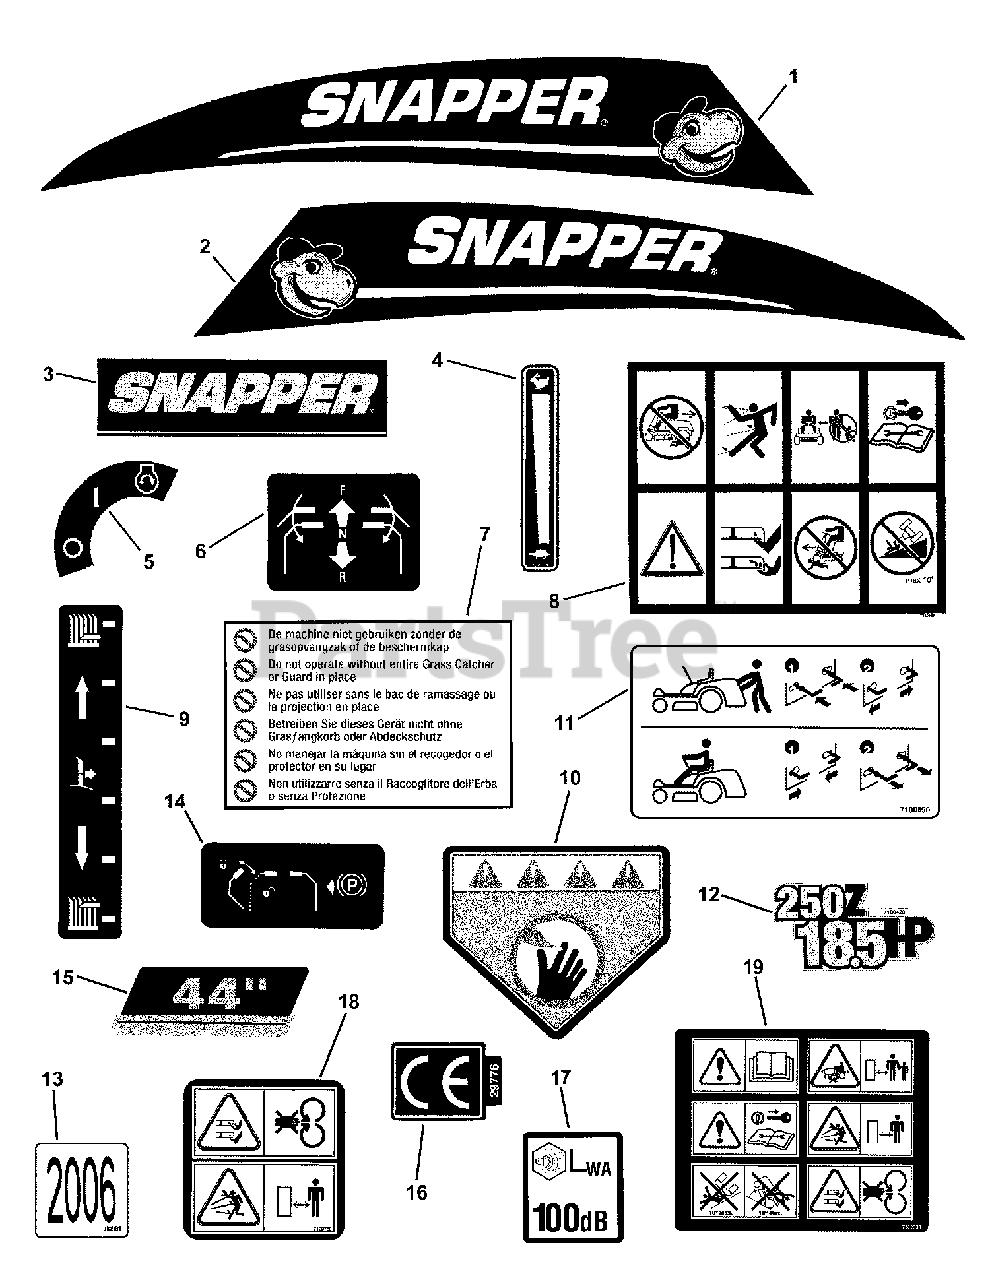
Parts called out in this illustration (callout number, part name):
1	DECAL, SNAPPER FENDER, RH
2	DECAL, SNAPPER FENDER, LH
3	DECAL, SNAPPER
4	DECAL, Throttle Control, RZT
5	DECAL, Ignition, RZT
6	DECAL, Motion Control, Symbols, ERZT
7	DECAL,Deck/Chute International Warning
8	DECAL, Safety Symbols- RZT
9	DECAL, Height of Cut, Symbols, ERZT
10	DECAL, Warning, International Symbol
11	DECAL, Roll Release, ERZT
12	DECAL, 250 Z 18.5HP RZT
13	DECAL, 2006 Year of Mfg.
14	DECAL, Park Brake, ERZT
15	DECAL-44"-Silver on Black w/stripe
16	DECAL, Euro Community (CE)
17	DECAL, Sound 100
18	DECAL, Deck Symbols, International
19	DECAL, Panel Symbols, Euro RZT
